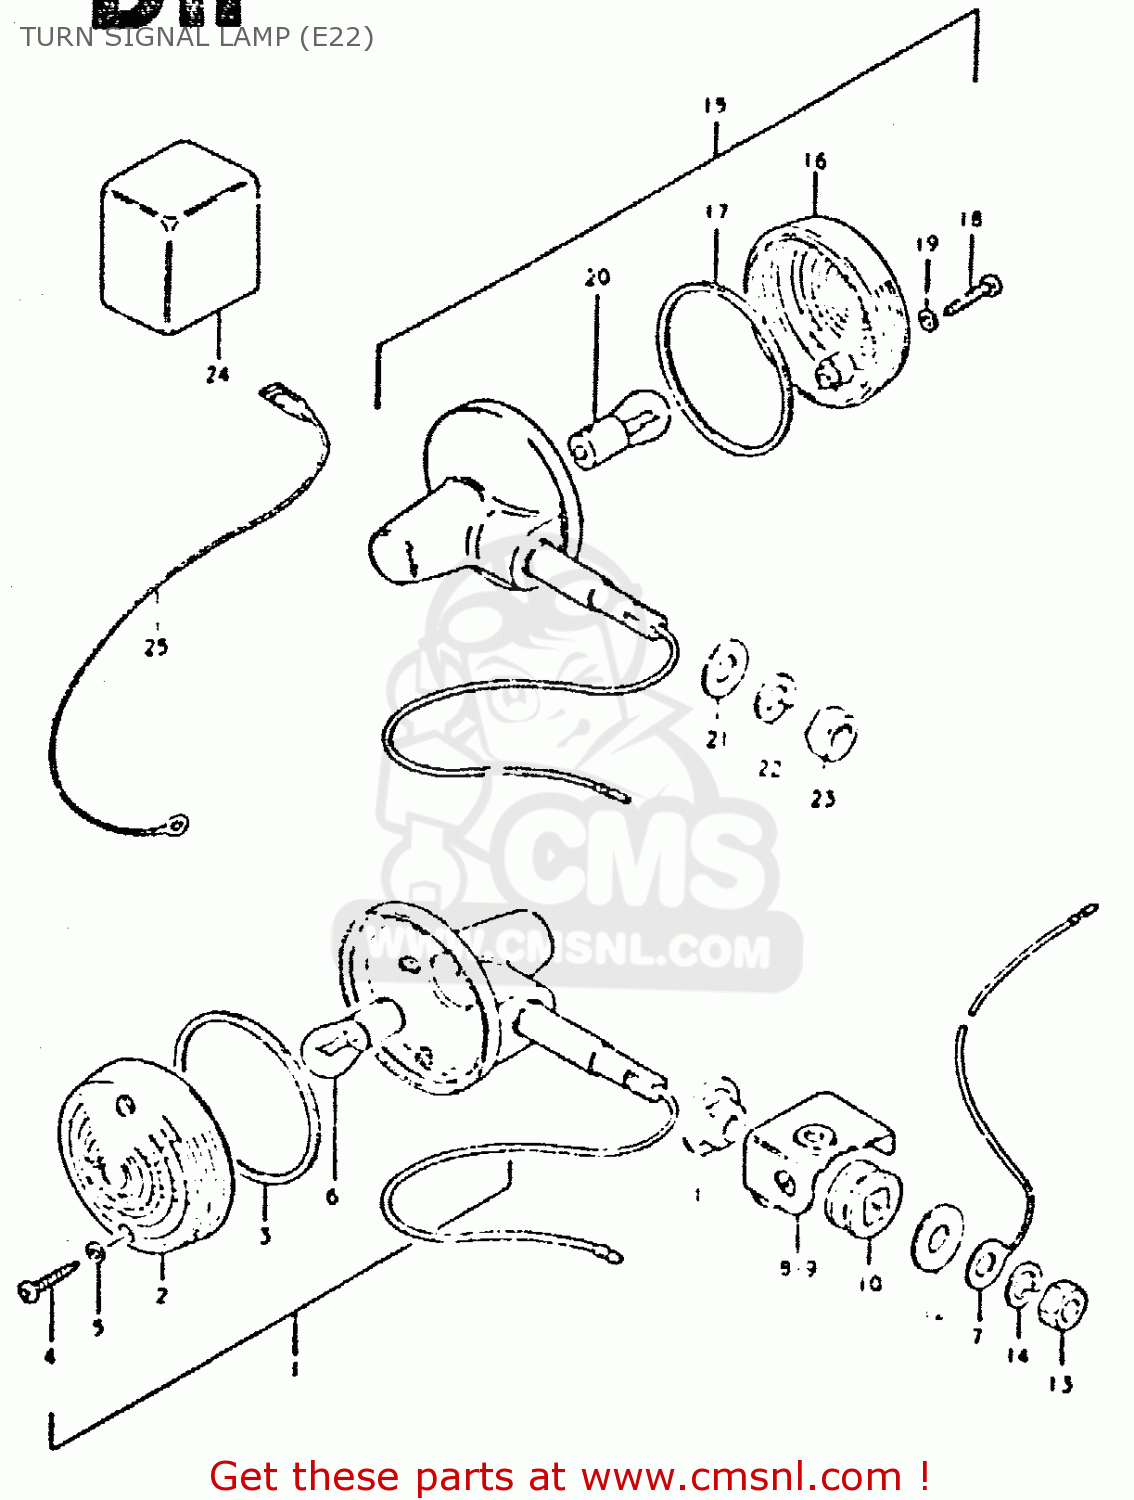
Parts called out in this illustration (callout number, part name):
1	LAMP ASSY,FR TURN SIGNAL
2	LENS
3	GASKET (NAS)
4	SCREW
5	GASKET (NAS)
6	BULB (6V,21W)
7	LEAD WIRE,EARTH
8	BRACKET, FRONT RH
9	BRACKET, FRONT LH
10	CUSHION
11	SPACER
12	WASHER (10.5X30X2.3)
13	NUT
14	LOCK WASHER
15	LAMP, REAR TURN SIGNAL
16	LENS
17	GASKET (NAS)
18	SCREW
19	GASKET (NAS)
20	BULB (6V,21W)
21	WASHER
22	LOCK WASHER
23	NUT
24	RELAY, TURN SIGNAL
25	LEAD WIRE, RELAY EARTH
